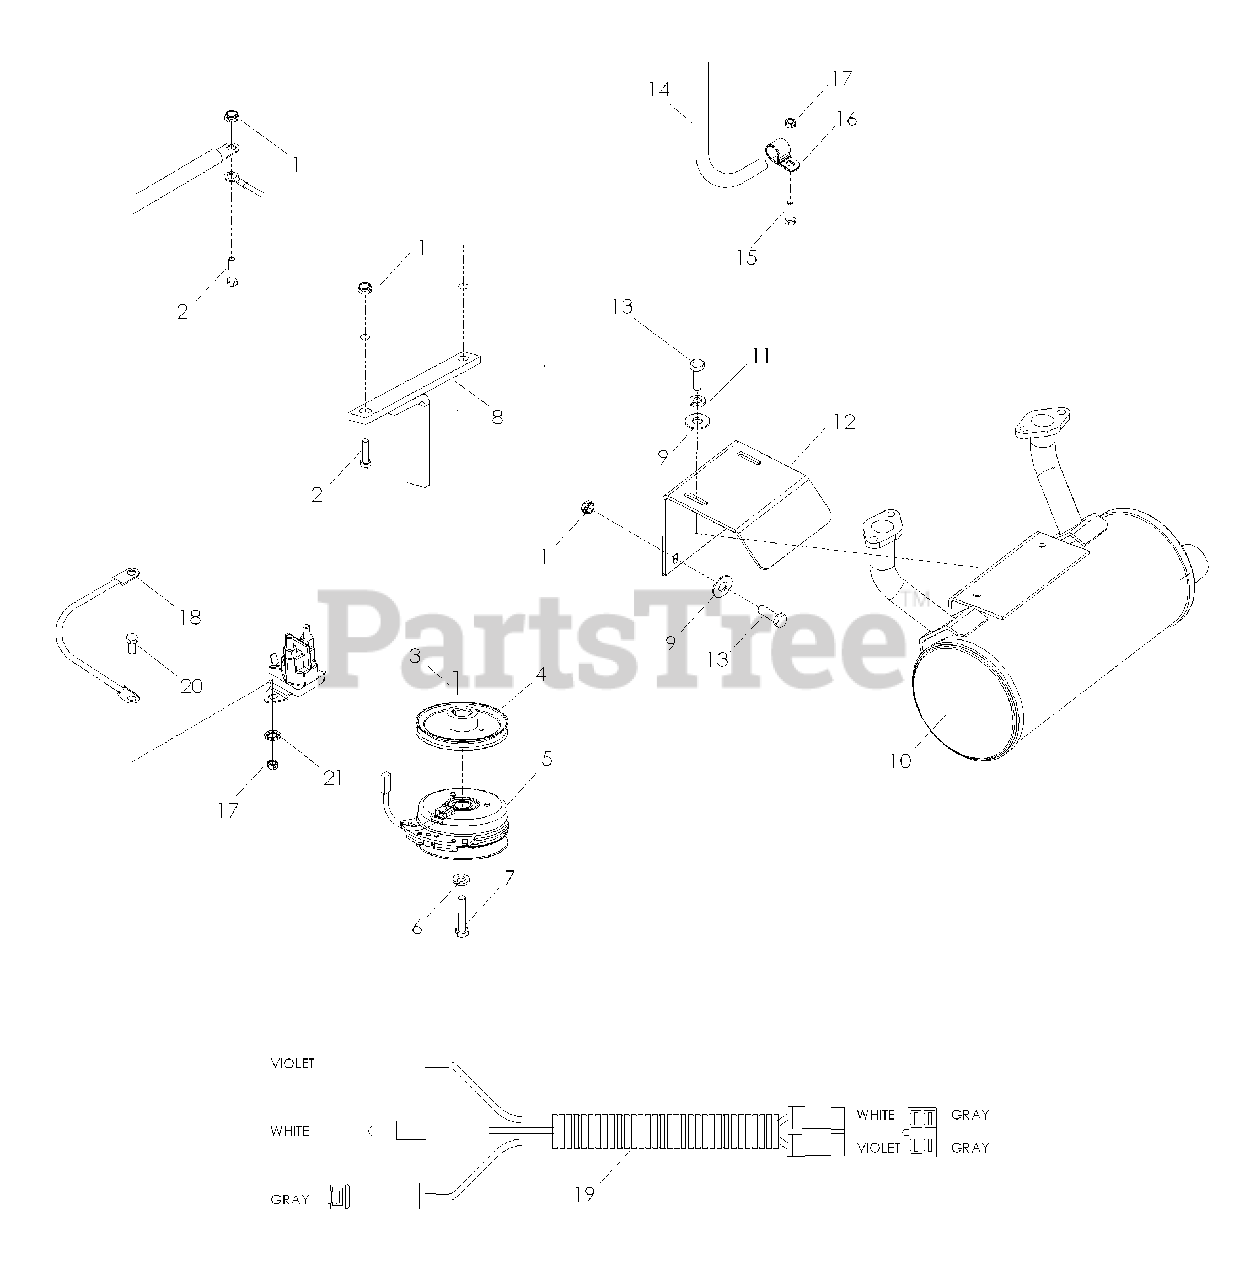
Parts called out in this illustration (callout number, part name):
1	NUT 5/16-18 HEX NYLOC
2	HCS 5/16 x 1 3/4
6	WASHER 7/16 LOCK
7	HCS 7/16 x 2 1/2
8	CLUTCH TIE DOWN
9	WASHER 5/16 FLAT
11	WASHER 5/16 LOCK
12	BRACKET MUFFLER
13	HCS 5/16-18 x 1
14	OIL DRAIN HOSE
15	HCS 1/4-20 x 3/4
17	NUT 1/4-20 CNTRLOCK
18	GROUND WIRE
20	HCS 1/4-20 x 5/8
21	WASHER, 1/4 INT TOOTH
